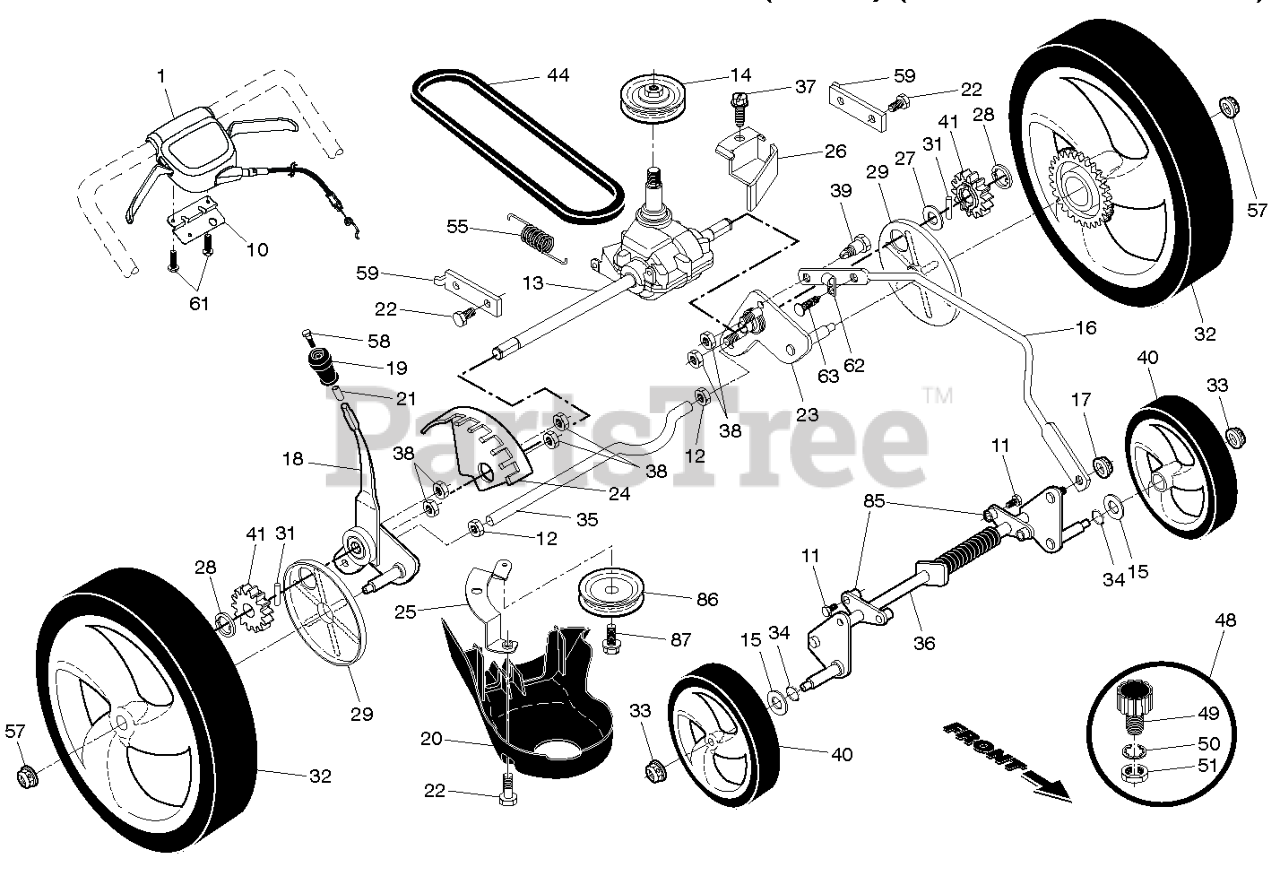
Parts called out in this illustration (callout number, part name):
1	DRIVE CONTROL ASSEMBLY INCUDES CABLE
10	MOUNTING BRCKT, DRIVE CONTROL
11	Screw, Rear Baffle
12	NUT, HEX
13	TRANSMISSION ASM
14	PULLEY DRIVE
15	Washer, Flat
16	ROD, CONNECTING
17	Nut, Hex
18	KIT, SELECTOR ASSEMBLY
19	KNOB, WHEEL ADJUSTER
20	DEBRIS SHIELD
22	BOLT.5/16-18HEX.WHS.HD.LCKSERR
23	WHEEL AXLE ASSEMBLY, LH
24	BRACKET, HEIGHT ADJUSTMENT
25	MOUNTING BRCKT, DEBRIS SHIELD
26	BELT KEEPER
27	Washer 17/32 x 3/4 x 16 Ga.
29	COVER, DUST, WHEEL
31	Pawl, Drive
32	WHEEL & TIRE ASSEMBLY, REAR
33	Nut, Hex, Flangelock 3/8-16
35	AXLE, REAR
36	AXLE, FRONT
37	SCREW, HI-LO THREAD #12 X 5/8
38	LOCKNUT, HEX 1/4-20
40	WHEEL & TIRE ASSEMBLY, FRONT
44	BELT, DRIVE
48	KIT, WATER WASHOUT ASSEMBLY
49	FITTING, WATER WASHOUT
50	WASHER, LOCK, INTERNAL TOOTH
51	LOCKNUT, HEX, WITH O-RING
55	SPRING, TENSION
57	Flanged Locknut, Hex
58	BOLT, SHOULDER
59	SUPPORT BRACKET
62	Clip, Cable
63	FASTENER, PUSH
85	SUPPORT BRACKET, FRONT AXLE
86	PULLEY, IDLER
